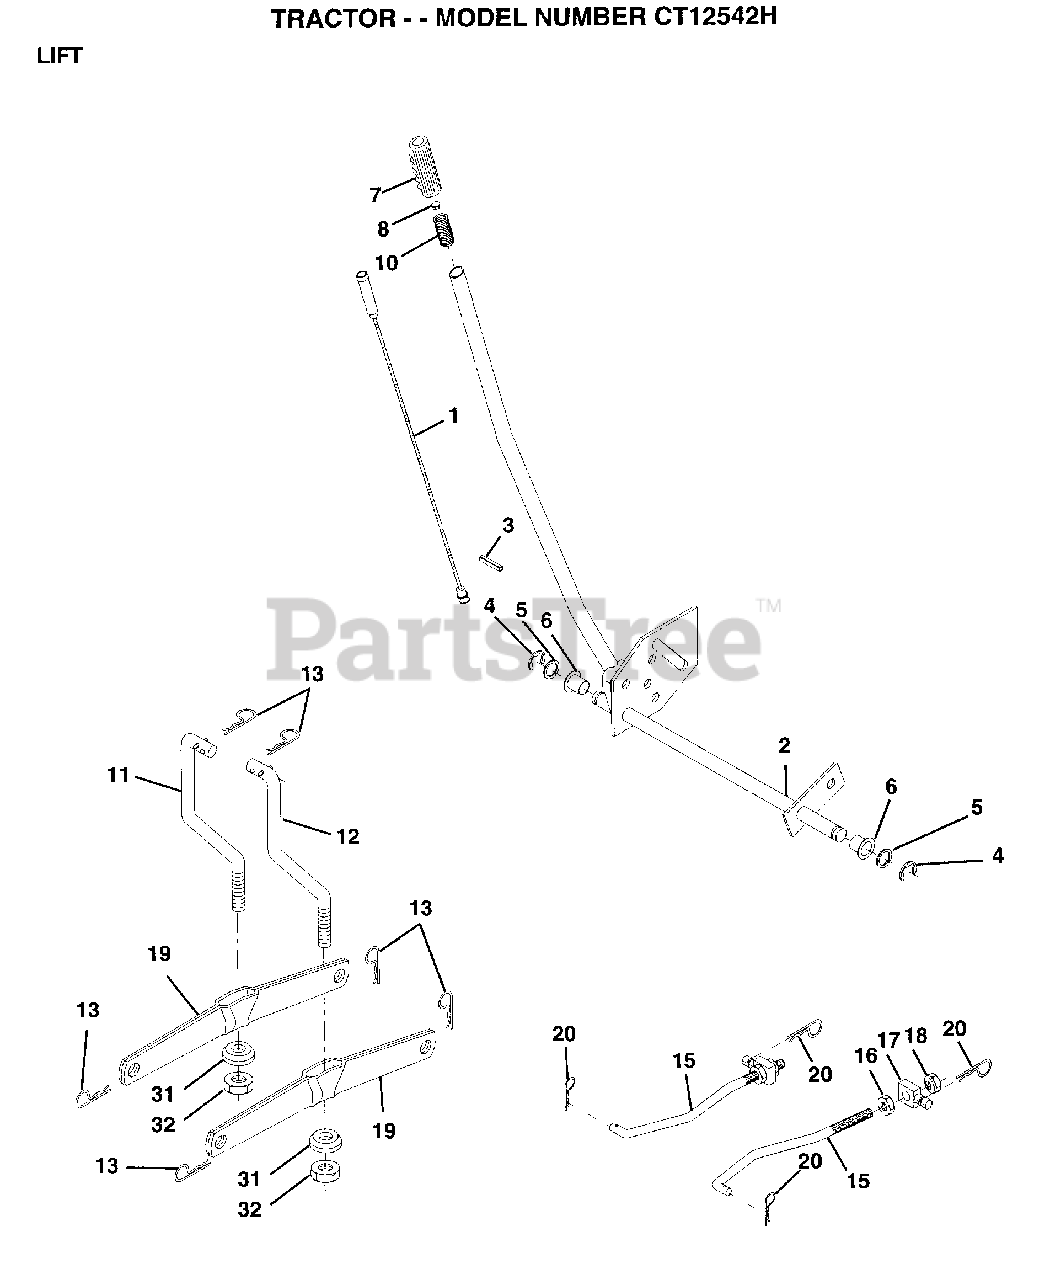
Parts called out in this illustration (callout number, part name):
1	WIRE ASM
2	HANDLE.LIFT.LH.
3	PIN GROOVE
5	WASHER
6	NYLON BEARING
7	GRIP
15	LINK.FRONT
16	NUT
17	TRUNION
18	NUT.LK.W/WSH.1/2.
19	ARM SUSP REAR
20	RETAINER.SPRING
31	BEARING PVT LH
32	NUT.CROWNLOCK.3/8
